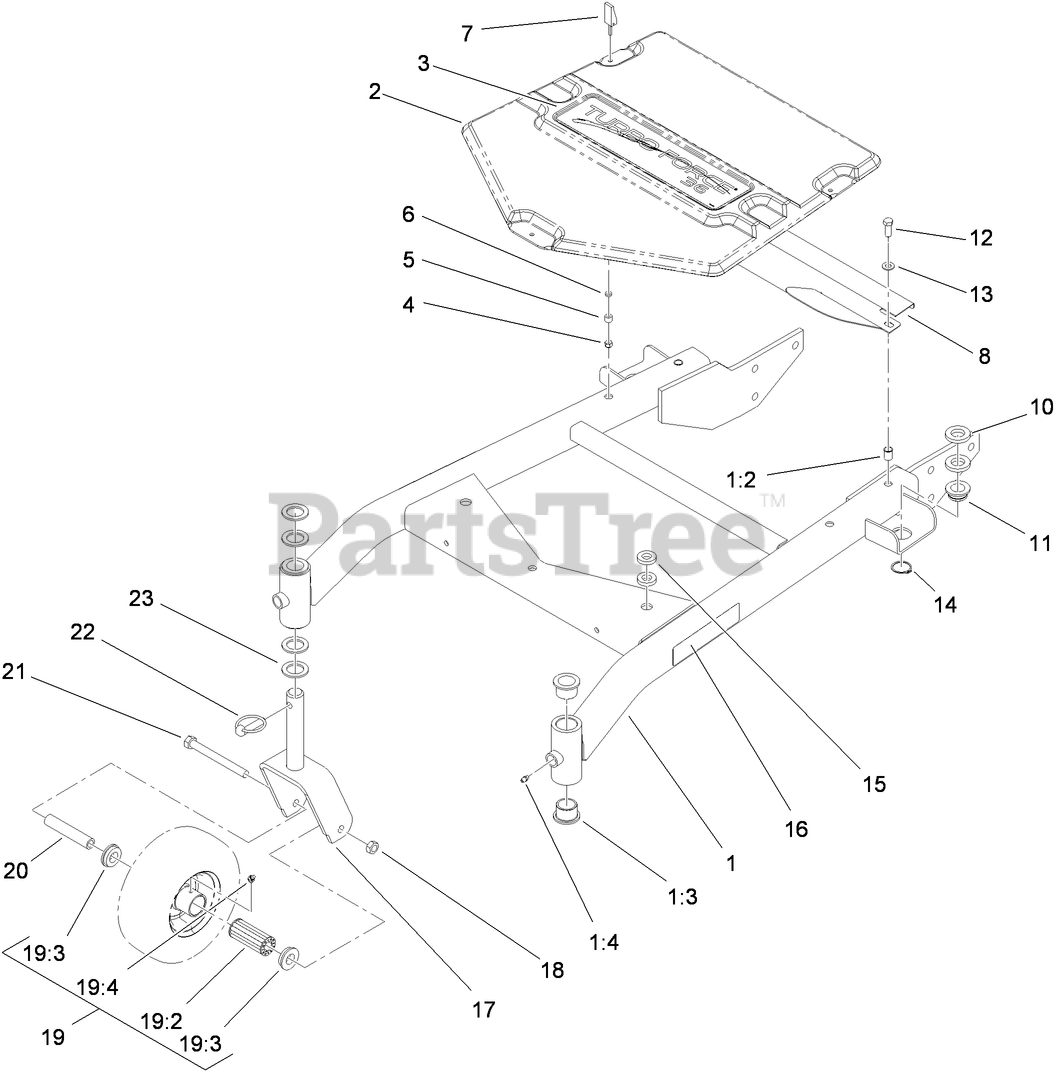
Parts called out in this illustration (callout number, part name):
1	CARRIER FRAME ASM
1:2	INSERT-NUT
1:3	BUSHING
1:4	FITTING-GREASE
2	COVER-FRAME, CARRIER
4	NUT-LOCK, HH
5	BUSHING-LATCH, SWELL
6	WASHER
7	HANDLE-LATCH, SWELL
8	SHIELD-BELT
10	SPACER-SUPPORT, DECK
11	BUSHING-DECK
12	SCREW-HH
13	WASHER-FLAT
14	RING-RETAINING
15	SPACER
16	DECAL-HOC
17	FORK-CASTOR
18	NUT-HEX
19	WHEEL AND TIRE ASM
19:2	BEARING-ROLLER
19:3	BUSHING
19:4	FITTING-GREASE
20	BUSHING-SPANNER
21	SCREW-HH
22	PIN-LYNCH
23	WASHER-THRUST
